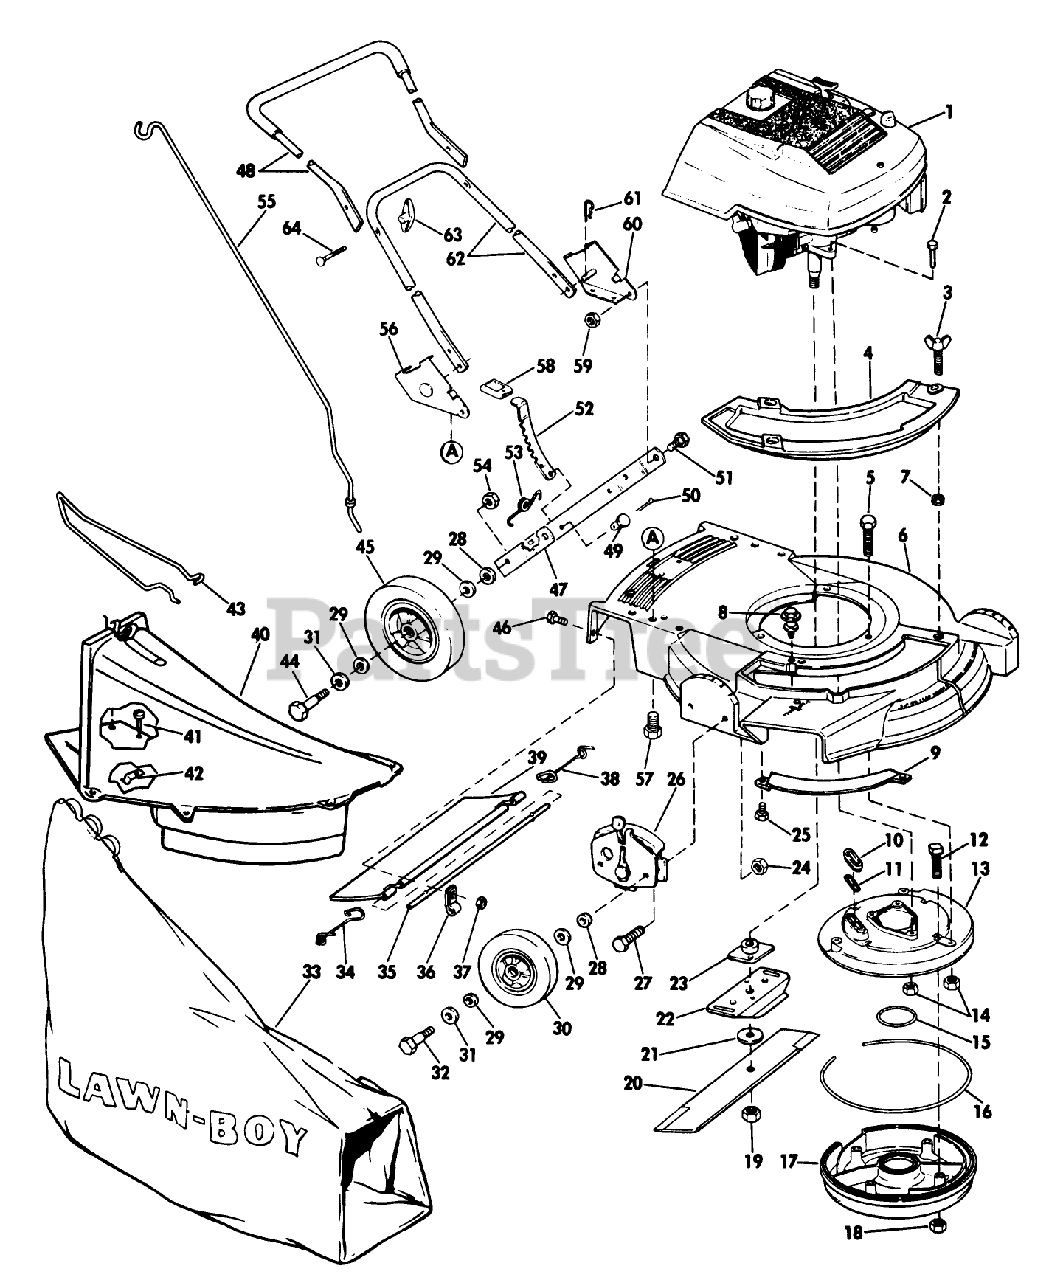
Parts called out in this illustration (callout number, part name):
3	WING SCREW LAWRE
5	SCREW V
9	TOE BAR 19"
9	BAR-TOE
11	GASKET S
14	NUT-LOCK F
16	Gasket Muffler (outside)
18	LOCKNUT E
19	NUT-BLADE
21	WASHER
23	PLATE AND COLLAR ASM
28	WASHER WROUGHT
32	BOLT WHEEL
33	ORD LB 89802 WHOLE GOODS
34	SPRING;TRAILING SHIELD RH
35	ROD T/SHIELD ADV WIRE
35	ROD 21" ADVANCE
36	CLAMP ROD KMC
38	SPRIG T/SHLD ASOC
51	BOLT-SHOULDER
53	SPRING N.A.S
54	LOCKNUT
55	ROD GRASSBAG
57	SCREW
61	HAIR PIN
63	NUT-WING
